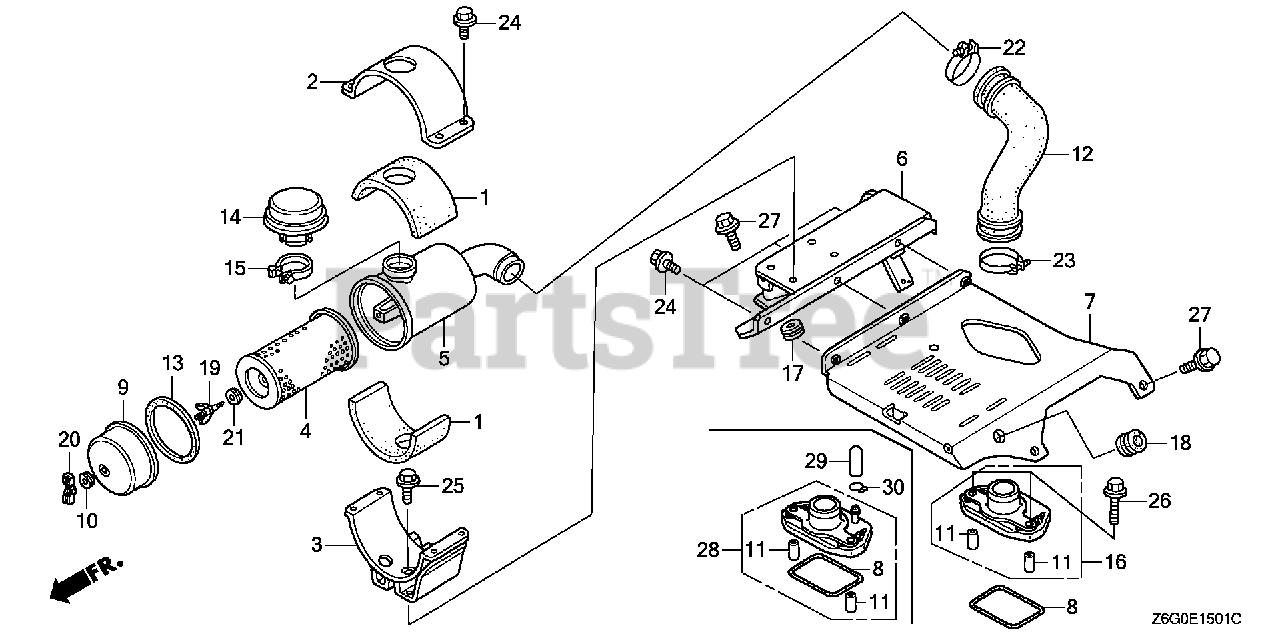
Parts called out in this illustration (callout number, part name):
1	RUBBER, AIR CLEANER HOLDER (UPPER)
2	HOLDER, AIR CLEANER (UPPER)
3	HOLDER, AIR CLEANER (LOWER)
4	ELEMENT, AIR CLEANER
5	HOUSING, AIR CLEANER (SNORKEL)
6	STAY A, AIR CLEANER (SNORKEL)
7	STAY B, AIR CLEANER (SNORKEL)
8	SEAL, AIR CLEANER HOUSING
9	COVER, AIR CLEANER
10	GROMMET, AIR CLEANER
11	COLLAR A, AIR CLEANER
12	TUBE, AIR CLEANER CONNECTING
13	SEAL, AIR CLEANER
15	CLAMP ASSY.
17	GROMMET, RESERVE TANK
19	BOLT, AIR CLEANER
20	WINGNUT (6MM) (BLACK)
21	WASHER, AIR CLEANER
22	BAND, AIR CLEANER CONNECTING TUBE (52)
23	BAND, AIR CLEANER CONNECTING TUBE (58)
24	BOLT, FLANGE (6X12)
25	BOLT, FLANGE (6X16)
26	BOLT, FLANGE (6X28)
27	BOLT, FLANGE (8X20)
28	JOINT B, CONNECTING TUBE
29	CAP, SEALING
30	CLIP, TUBE (B10)
